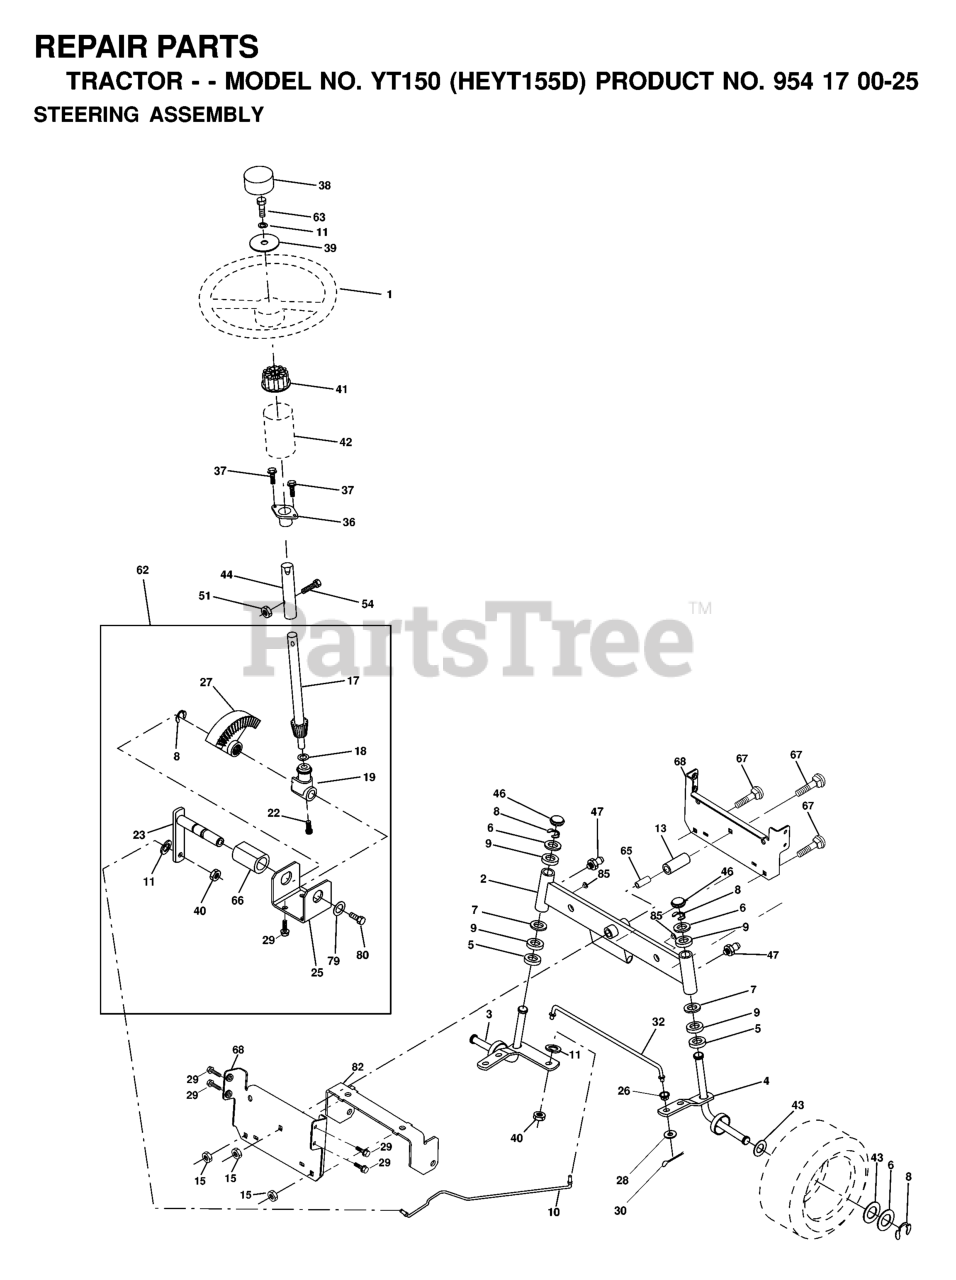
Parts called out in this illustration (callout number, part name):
1	GEARCASE ASM.RH.W/BEARING 2002
2	SPACER.GEARCASE
3	GEAR.REVERSE.8HP
5	NEEDLE BEARING
6	SPROCKET ASMBLY, TINE
7	SPROCKET ASMBLY W/BEARINGS
9	SHAFT.REDUCTION.TILLER
10	CHAIN.ROLLER.TILLER
11	SPRING-SHIFT CRT
12	STEEL BALL KIT
13	SHIFT FORK TI
14	SHAFT.SHIFT.1.00 PINION
16	WASHER, SEAL (2 2)
17	THRUST WASHER
18	BEARING TI
19	SHAFT INPUT
21	SHAFT.ASM.TINE.21
22	SPACER 1.008X1-3/4X.645
23	GEAR.PINION.INPUT
24	NEEDLE BRNG LT
25	GASKET.GEARCASE.TILLER.8HP
27	GEAR, CLUSTER CRT
28	REVERSE GEAR
29	GEAR ASMBLY, REVERSE IDLER
30	NEEDLE BEARING TI
32	SHAFT, REVERSE IDLER
33	SHAFT, REDUCTION
34	SPACER.765 X 1.12 X .380.
35	SPACER, GROUND DRIVE RH
36	SHAFT ASSY CRT
37	BRACKET ASM.SHIFT.CRT
38	SPACER, GROUND DRIVE
41	SEAL ASM, OIL
42	LOCKWASHER
43	NUT.ASF.HEX.7/16
44	GEARCASE ASM.LH.W/BEARING 2002
45	BOLT.5/16HEX.WHS.HD
48	SCREW 5/16-18X4
60	FITTING.GREASE.TAPERED
61	SPACER.1.015 X 1.50 X .765
